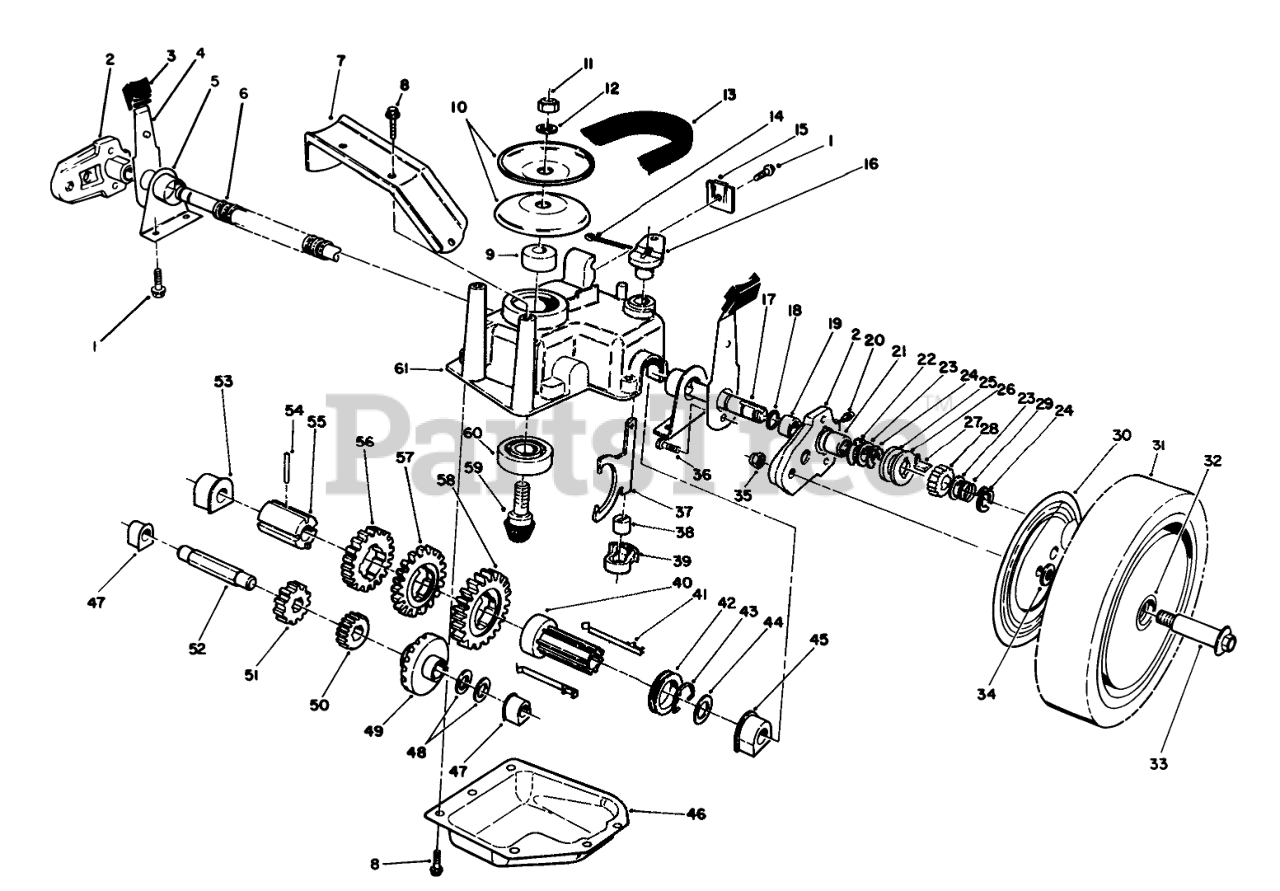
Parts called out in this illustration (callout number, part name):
1	SCREW-HWHTF
2	Pivot Arm Assembly (Incl. Ref. #19-21)
3	KNOB-ARM
4	SPRING ARM ASM
5	Cap-End
6	CONDUIT-CONVOLUTED, SPLIT
7	Bracket-BeltGuide
8	SCREW-HWHTF
9	SPACER
10	Pulley Half
11	NUT-HEX
12	WASHER-FLAT
13	V-BELT
14	PIN-COTTER
15	Cable Clamp
16	SHIFT LEVER
17	SHAFT-OUTPUT
18	O-RING
19	BUSHING
20	FITTING-GREASE
21	BEARING-ROLLER
22	WASHER-ARM, PIVOT
23	WASHER-THRUST, KEYED
24	RING-CLIP, LOCKING
25	RING-FRICTION
26	WASHER-CLUTCH
27	KEY-ROCKING, LH
28	GEAR-PINION
29	SPRING-COMPRESSION
30	WHEEL COVER
31	Wheel Tire & Gear Assy. (Incl. Ref. #32)
32	BUSHING
33	WHEEL BOLT
34	WASHER
35	Nut
36	SCREW-HSH, THREAD FORMING
37	YOKE-SHIFT
38	BUSHING-YOKE
39	RETAINER-FORK, SHIFT
40	Sleeve-Shift Key
41	SHIFT KEY
42	SHIFT COLLAR
43	CLIP-SPRING
44	WASHER-PLAIN
45	BUSHING-OUTPUT
46	Cover-Gearcase
47	BUSHING
48	WASHER-THRUST
49	Gear-Bevel
50	PINION-20T
51	PINION-25T
52	SHAFT-INTERMEDIATE
53	BUSHING
54	PIN-SPRING
55	SLEEVE-GEAR
56	GEAR-39T
57	GEAR-44T
58	GEAR-49T
59	Gear-Pinion
60	BEARING-BALL
61	CASE-GEAR, UPPER
